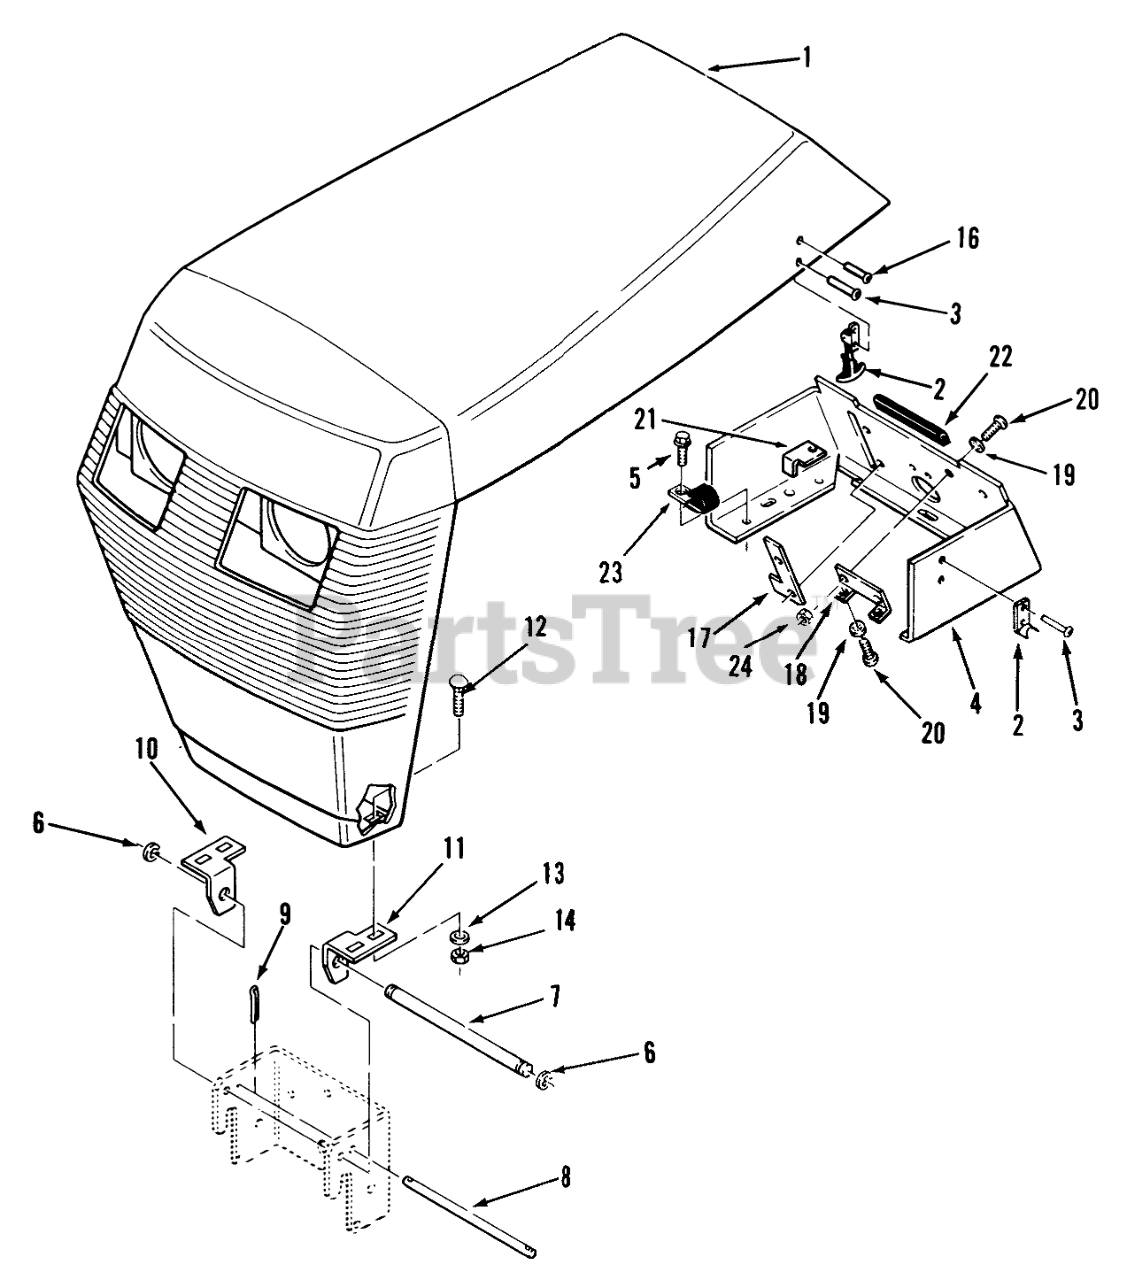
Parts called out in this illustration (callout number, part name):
1	Hood
2	LATCH-FLEX BLK ASS'Y
3	RIVET-POP
4	Console 310-8
5	SCREW
6	RING-RETAINING
7	ROD-GRILL PIVOT
8	ROD-HOOD STOP
9	Cotter Pin
10	BRACKET-GRILL, R H
11	BRACKET-GRILL, LH
12	SCREW-CARR
13	WASHER-FLAT
14	NUT-LOCK
16	POPRIVET 1/8X 1/8 BK
17	Washer
18	BRACKET
19	Washer-Lock
20	SCREW
21	STOP-PTO
22	EDGING-CONSOLE
23	J-CLIP
24	NUT-HEX
